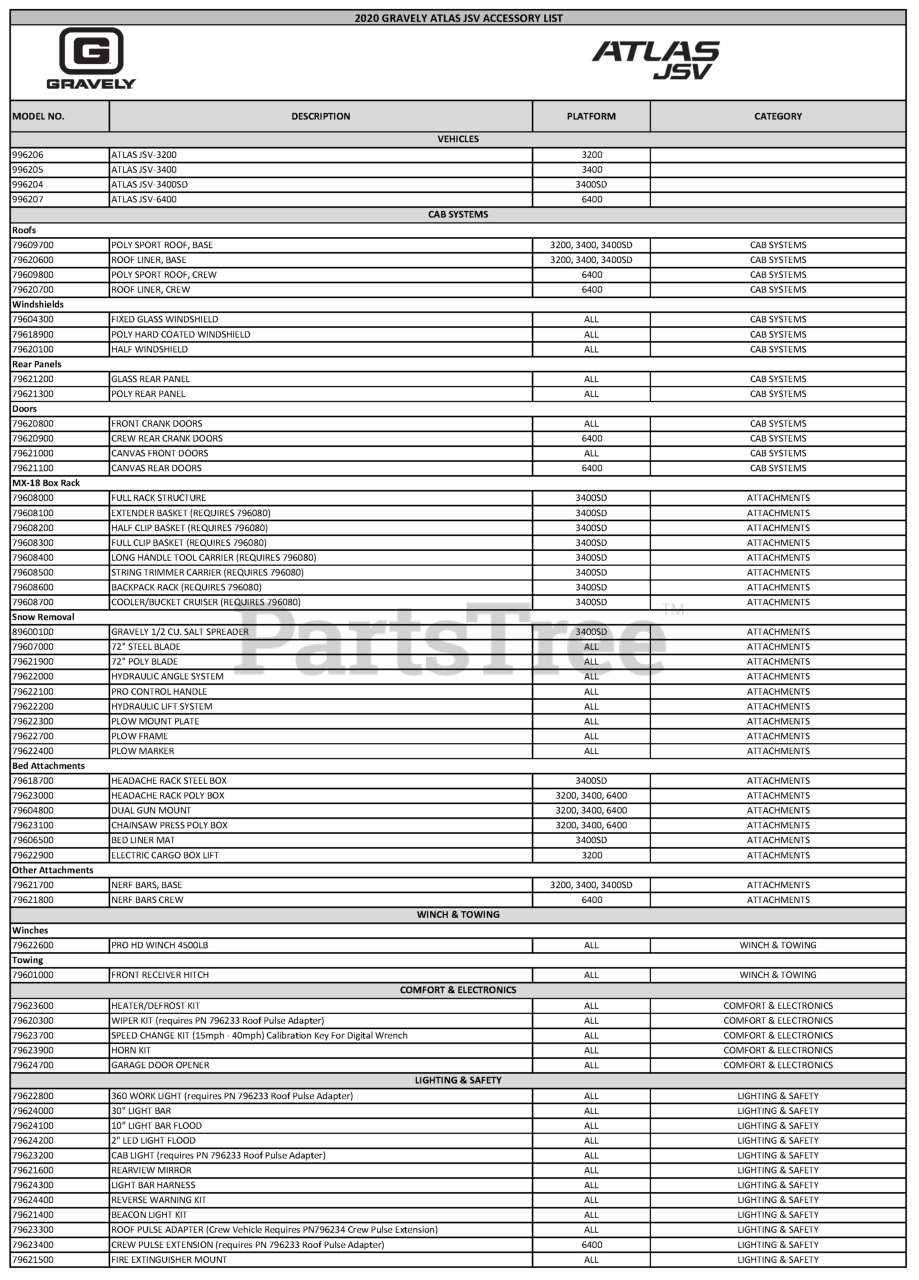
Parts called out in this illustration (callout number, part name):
1	POLY SPORT ROOF, BASE
2	ROOF LINER, BASE
3	POLY SPORT ROOF, CREW
4	ROOF LINER, CREW
5	FIXED GLASS WINDSHIELD
6	POLY HARD COATED WINDSHIELD
7	HALF WINDSHIELD
8	GLASS REAR PANEL
9	POLY REAR PANEL
10	FRONT CRANK DOORS
11	CREW REAR CRANK DOORS
12	CANVAS FRONT DOORS
13	CANVAS REAR DOORS
14	FULL RACK STRUCTURE
15	EXTENDER BASKET (REQUIRES 796080)
16	HALF CLIP BASKET (REQUIRES 796080)
17	FULL CLIP BASKET (REQUIRES 796080)
18	LONG HANDLE TOOL CARRIER (REQUIRES 796080)
19	STRING TRIMMER CARRIER (REQUIRES 796080)
20	BACKPACK RACK (REQUIRES 796080)
21	COOLER/BUCKET CRUISER (REQUIRES 796080)
22	GRAVELY 1/2 CU. SALT SPREADER
23	72" STEEL BLADE
24	72" POLY BLADE
25	HYDRAULIC ANGLE SYSTEM
26	PRO CONTROL HANDLE
27	HYDRAULIC LIFT SYSTEM
28	PLOW MOUNT PLATE
29	PLOW FRAME
30	PLOW MARKER
31	HEADACHE RACK STEEL BOX
32	HEADACHE RACK POLY BOX
33	DUAL GUN MOUNT
34	CHAINSAW PRESS POLY BOX
35	BED LINER MAT
36	ELECTRIC CARGO BOX LIFT
37	NERF BARS, BASE
38	NERF BARS CREW
39	PRO HD WINCH 4500LB
40	FRONT RECEIVER HITCH
41	HEATER/DEFROST KIT
42	WIPER KIT (requires PN 796233 Roof Pulse Adapter)
43	SPEED CHANGE KIT (15mph - 40mph) Calibration Key For Digital Wrench
44	HORN KIT
45	GARAGE DOOR OPENER
46	360 WORK LIGHT (requires PN 796233 Roof Pulse Adapter)
47	30" LIGHT BAR
48	10" LIGHT BAR FLOOD
49	2" LED LIGHT FLOOD
50	CAB LIGHT (requires PN 796233 Roof Pulse Adapter)
51	REARVIEW MIRROR
52	LIGHT BAR HARNESS
53	REVERSE WARNING KIT
54	BEACON LIGHT KIT
55	ROOF PULSE ADAPTER (Crew Vehicle Requires PN796234 Crew Pulse Extension)
56	CREW PULSE EXTENSION (requires PN 796233 Roof Pulse Adapter)
57	FIRE EXTINGUISHER MOUNT
